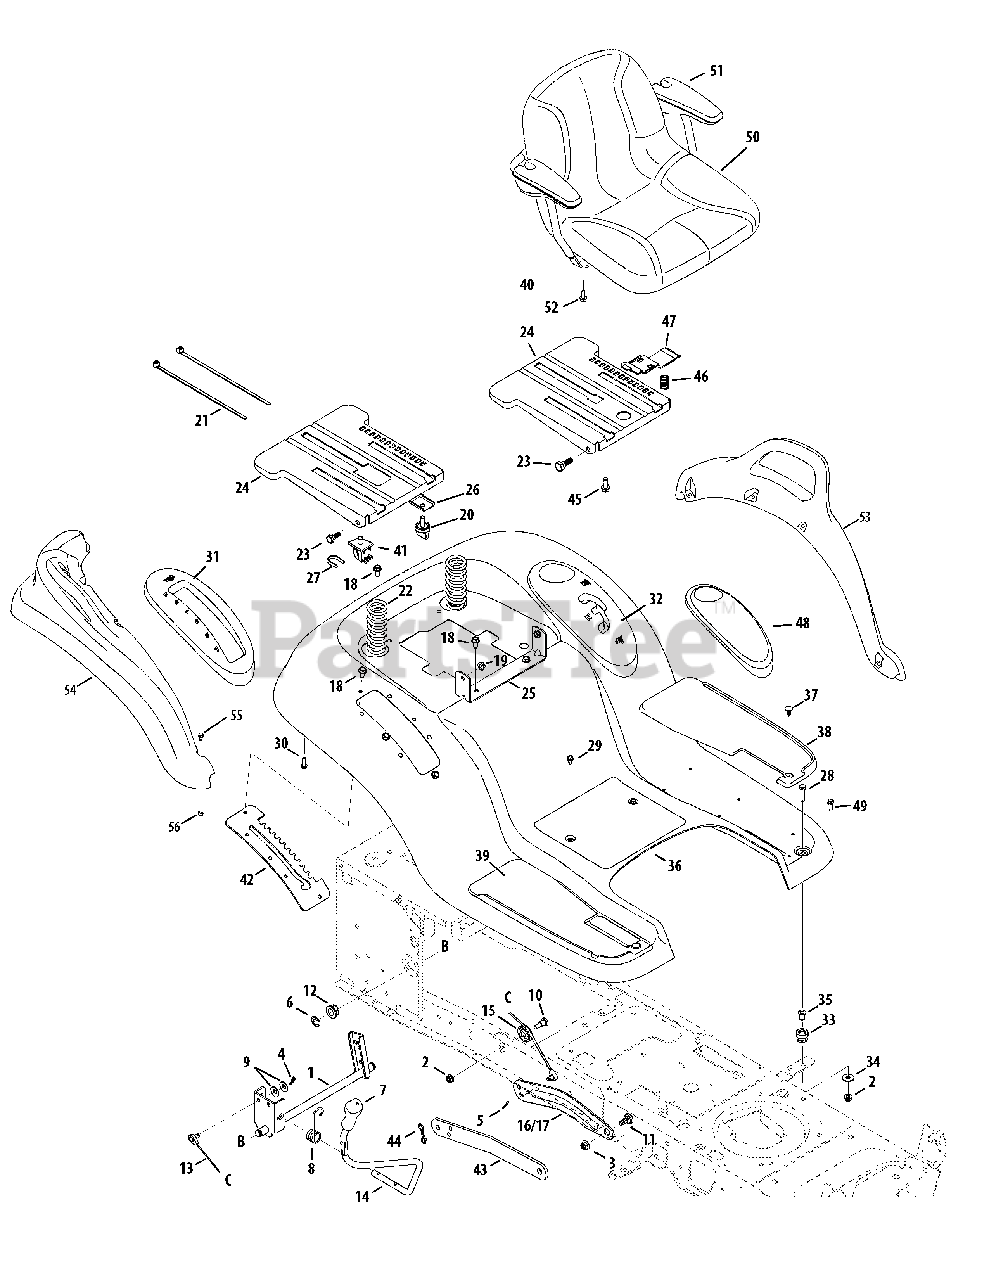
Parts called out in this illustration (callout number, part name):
1	Lift Shaft Ass’y
2	Flange Locknut 5/16-18 Gr. F, Nylon
3	Flange Lock-Nut 3/8-16 Gr. F Nylon
4	Int. Cotter Pin .072 x 1.13" Lg.
5	Bow-Tie Cotter Pin
6	E-ring .625 Shaft
7	Handle Grip
8	Torsion Spring
9	Cupped Washer .375 ID x .870 OD x .063
10	Shoulder Screw. .437 Dia x .47
11	Shoulder Screw .500 x .25 (46"/50")
11	Shoulder Bolt 3/8-16 x .625 (38"/42")
12	Hex Flange Bearing .630 ID
13	Lift Cable, 16.16
14	Lift Handle
15	Roller Pulley
16	Lift Arm RH
17	Lift Arm LH
18	Hex Wash Hd. Tapp Screw. 5/16-18 x .75
19	Hex Flange L-Nut 5/16-18
21	Cable Tie
22	Compression Spring 1.50 x 3.9 x .20
23	Shoulder Screw
24	Seat Mount ing Bracket
25	Seat Pivot Bracket
26	Seat Bracket, Knob adjustment
27	Switch Retaining Clip
28	Hex Bolt 5/16-18 x 1.25
29	Hex Wash S-Tapp Screw 1/4-20 x .50
30	Hex Tapp Screw 1/4 x .75" Lg.
31	Lift Lever Cover
32	Shift Lever Cover
33	Grommet .4375 ID x .75
34	Flat Washer .344 ID x 1.0
35	Flange Spacer .3125 x .4375 x .625
37	Foot Pad Clips
38	Foot Pad LH
39	Foot Pad RH
41	Seat Switch
42	Lift Bracket 6 positions (w/Electric pto)
43	Lift Link (46"/50")
44	Bow-Tie Cotter Pin (46")
45	Hex. Hd. Flg. Screw. 3/8-16 x .875
46	Compression Spring .68 x 1.065 x .055
47	Seat adjustment Lever
48	Cover (Hydrostatic Models only)
49	Hex Wash. Hd. Screw. 5/16-18 x .75 Gr. F Nyl.
50	Seat, High Back, Black (w/arm rest option)
51	Arm Rest (incl. R&L)
52	Pan TT Screw 5/16-18 x .75
53	Fender Cover LH
54	Fender Cover RH
